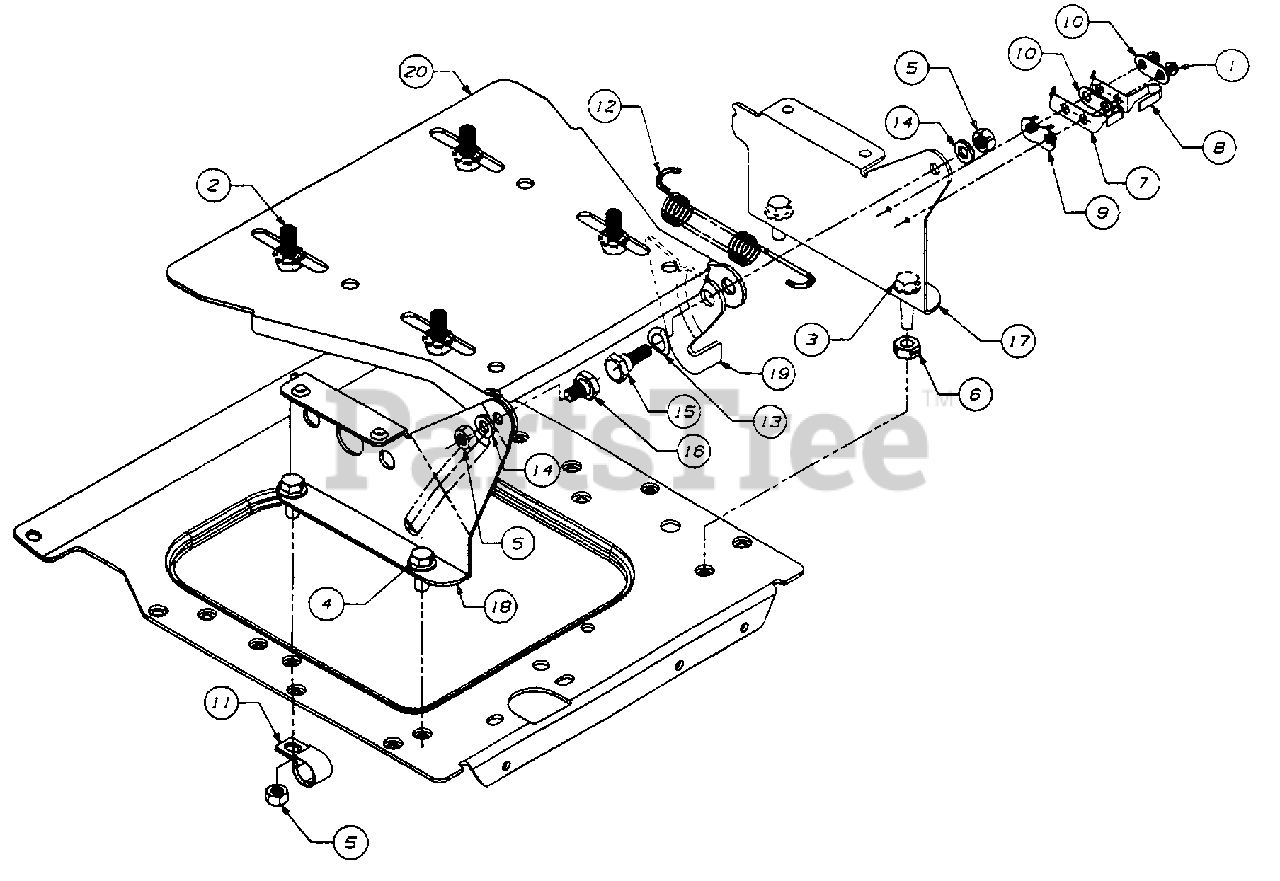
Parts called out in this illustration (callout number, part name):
1	Hex AB-Tap Scr. #8 .5" Lg.
2	Hex TT-Tap Scr. 3/8-16 x .62"
3	Hex TT-Tap Scr. 5/16-18 x 1.25"
4	Hex Flange Scr. 5/16-24 x .75"
5	Hex Nut 5/16-18 Thd.
6	Hex L-Nut 5/16-18 Thd.
7	Seat Safety Switch
8	Seat Safety Switch
9	Insulator Boss Plate
10	Insulator Plate
11	Clamp
12	Ext. Spring 5.31" Lg.
13	Spr. Wash. 7/16" I.D.
14	L-Wash. 5/16" I.D.
15	Shld. Bolt .437" x .27" Lg.
16	Shld. Bolt .437" x 1.62" Lg.
17	Seat Pivot Support - L.H.
18	Seat Pivot Support - R.H.
19	Seat Lift Brkt.
